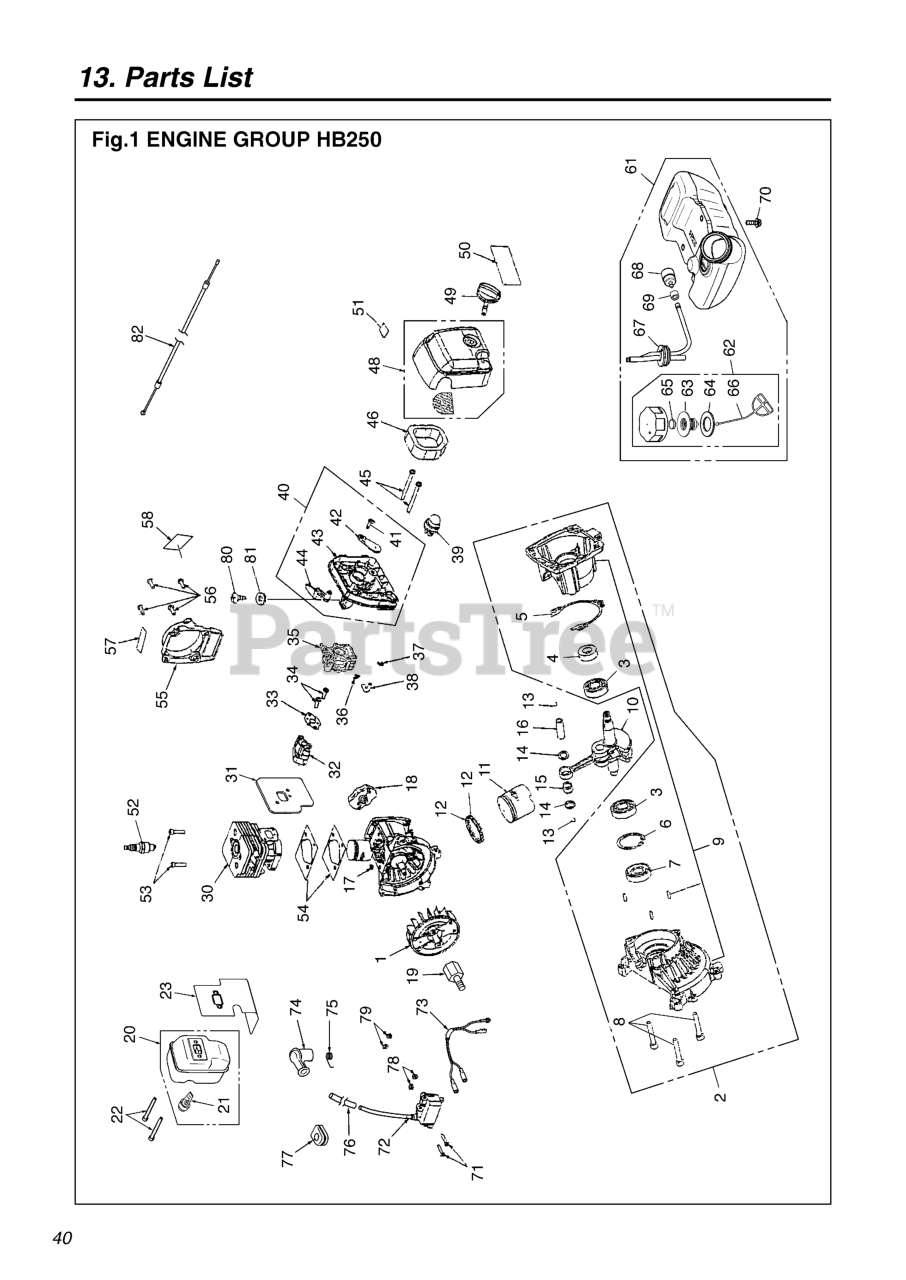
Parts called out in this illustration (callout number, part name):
1	ROTOR
2	CRANKCASE & SHAFT ASS
3	BEARING
4	SEAL (REPLACES 5987501)
5	GASKET, CRANKCASE
6	RING
7	SEAL
9	CRANKCASE ASS
10	CRANKSHAFT ASS
11	PISTON
12	RING, PISTON
13	CLIP RING
14	WASHER
15	NEEDLE BEARING
16	WRIST PIN
18	PULLEY ASS
19	EXTENSION
20	MUFFLER-ASSY
21	ARRESTER
22	BOLT,TORX, M5X70
23	GASKET
30	CYLINDER
31	GASKET, INSULATOR
32	INSULATOR
33	GASKET, CARBURETOR
34	SCREW, TORX
35	CARBURETOR
36	CLIP, HOSE
37	CLIP, HOSE
38	PLASTIC RUBBER, TUBING
39	PRIMER ASS
40	CHOKE LEVER & PLATE ASS
41	SCREW, TORX
42	CHOKE PLATE
43	CARBURETOR PLATE
44	CHOKE LEVER
45	BOLT, CARBURETOR
46	ELEMENT
48	COVER ASS
49	KNOB
51	LABEL, START
52	SPARK PLUG
53	CAP SCREW
54	GASKET, CYLINDER
55	RECOIL ASSY
56	SCREW, TORX
57	LABEL, E START
58	DECAL, EMISSION
61	TANK-A
62	CAP ASSY (RPLS -85201)
63	HOLDER (REPLACES -85230)
64	PACKING
65	FILTER
66	STOPPER
67	PIPE-C
68	FILTER ASSY
70	BOLT
71	BOLT, TORX
72	COIL & BOLT ASSY.
74	CAP
75	SPRING
76	TUBE
77	GROMMET
78	SPACER
80	SCREW
81	WASHER
82	CABLE COMP (RPLS, -83100)
